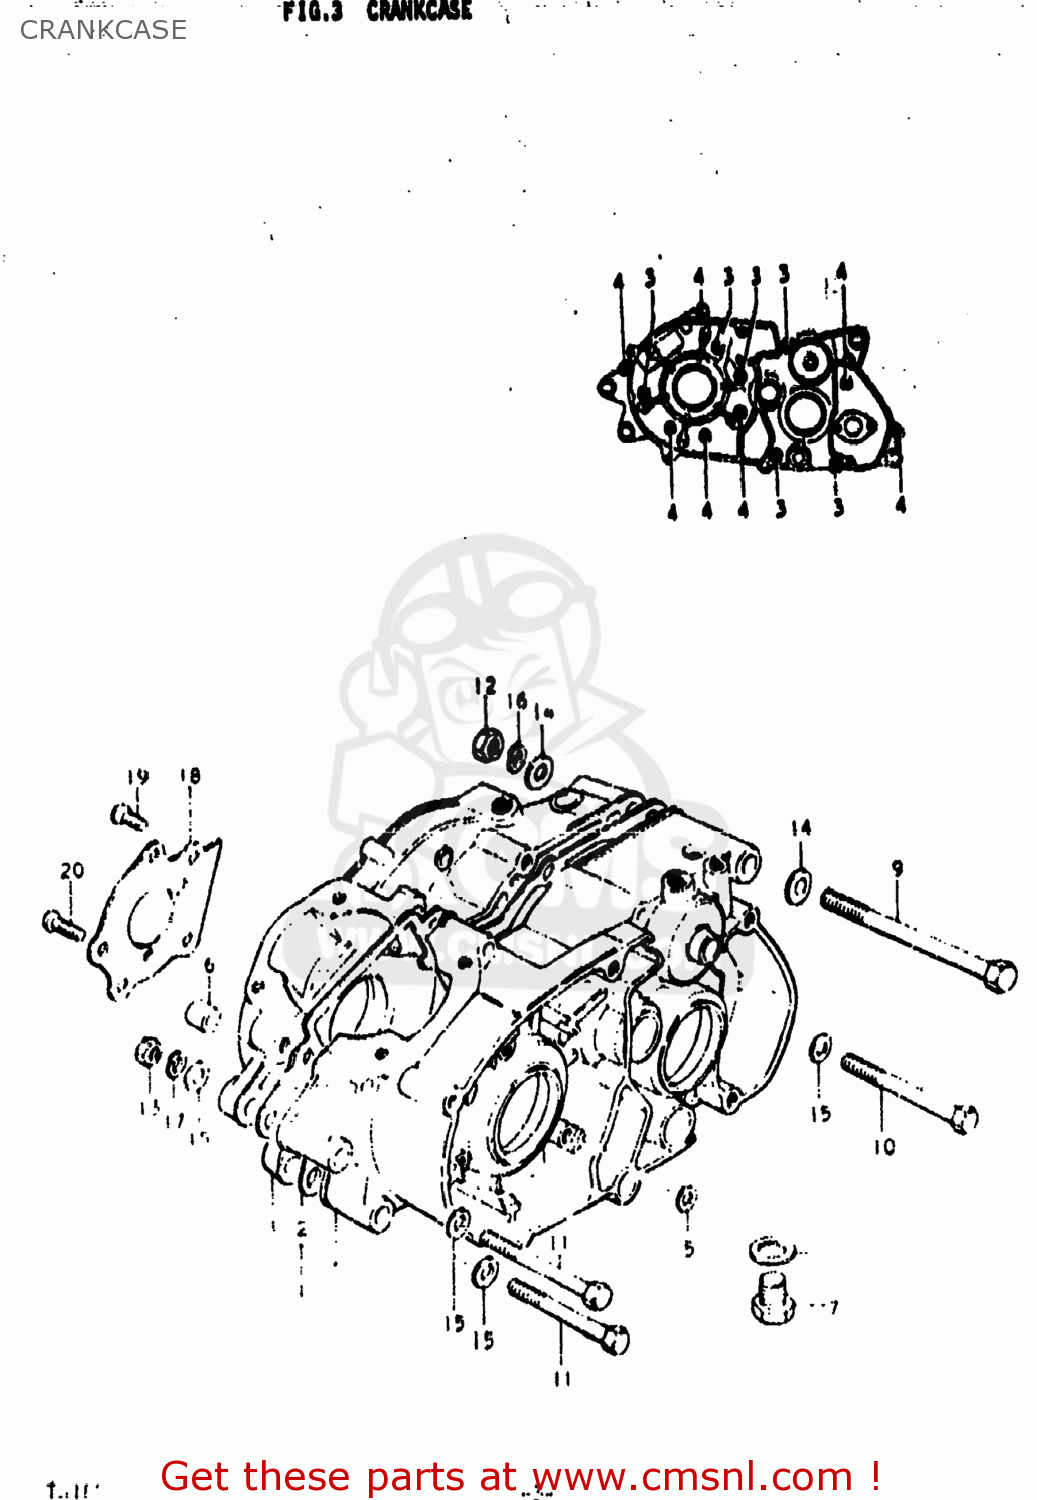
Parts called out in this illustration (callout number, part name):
1	CRANKCASE SET
2	GASKET,CRANKCASE (NAS)
3	SCREW
4	SCREW (6X45)
5	WASHER
6	PIN
7	PLUG
8	GASKET(14X19.2X2) (NAS)
9	BOLT 10X120
10	BOLT 8X120
11	BOLT
12	NUT
13	NUT
14	WASHER
15	WASHER
16	LOCK WASHER
17	LOCK WASHER
18	PLATE,OIL RESERVOIR
19	SCREW
20	SCREW
